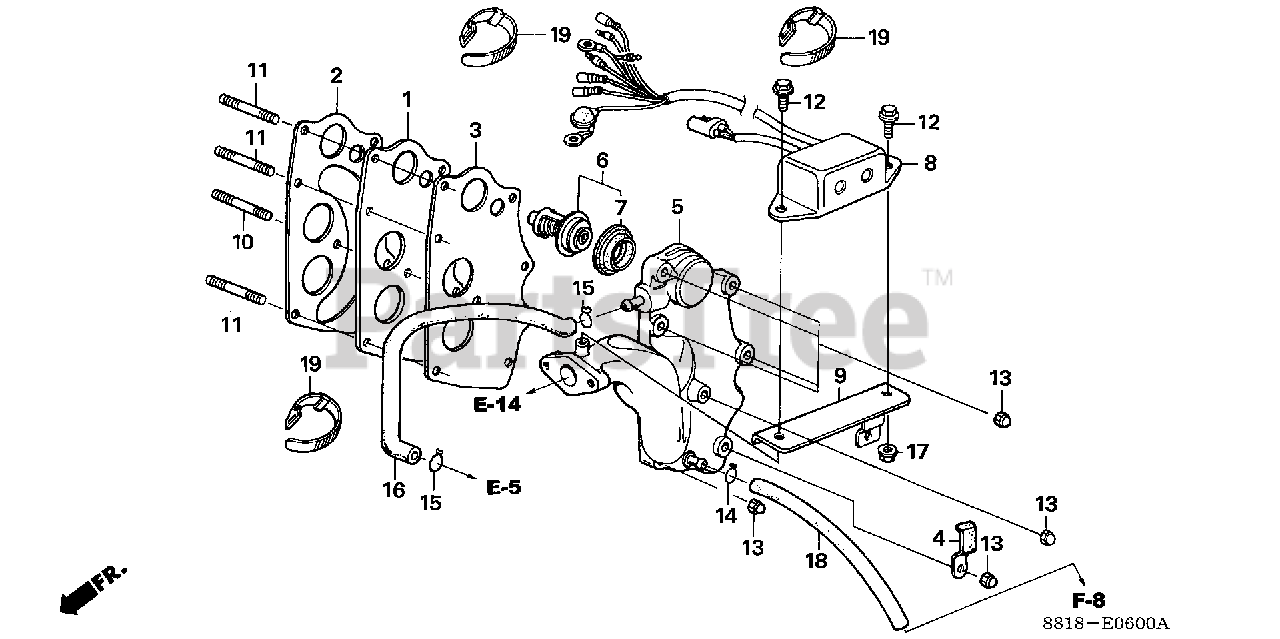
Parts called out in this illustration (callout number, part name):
1	PLATE, EX. CHAMBER
2	GASKET, EX. CHAMBER
3	GASKET, EX. CHAMBER
4	CLIP B, CORD
5	MANIFOLD, IN. *NH8* (DARK GRAY)
6	THERMOSTAT ASSY.
7	RUBBER, THERMOSTAT
8	MODULE, IGNITION CONTROL (CDI)
9	STAY, IGNITION CONTROL MODULE (CDI)
10	BOLT, STUD (6X48)
11	BOLT, STUD (6X36)
12	BOLT, FLANGE (6X12)
13	NUT, CAP (6MM)
14	CLIP, TUBE (B8)
15	CLIP, TUBE (B12)
16	TUBE, BYPASS
17	NUT, HEX. (6MM)
18	BULK HOSE, VACUUM (5X3000) (5X250)
19	BAND B1, WIRE
